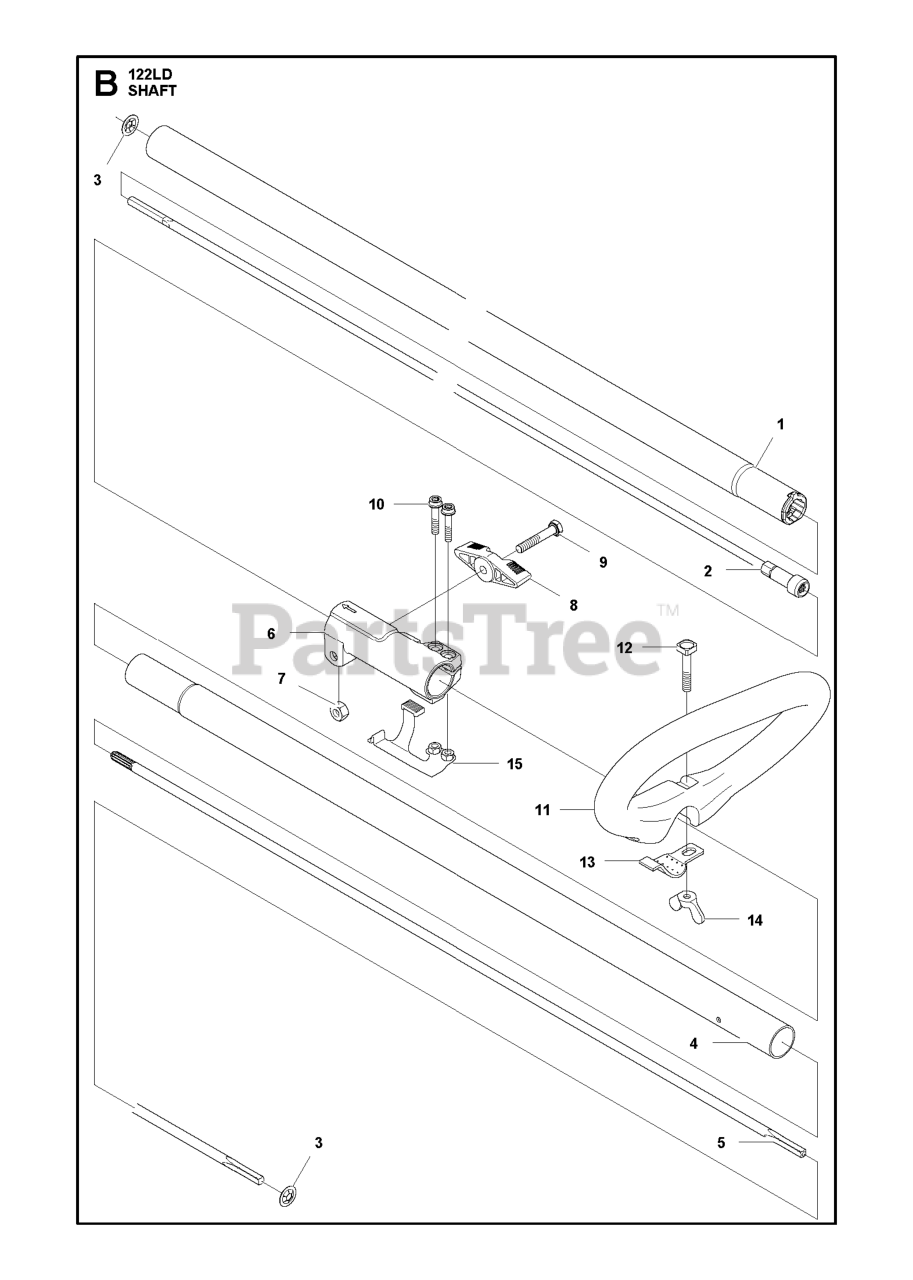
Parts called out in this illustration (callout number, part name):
2	DRIVE SHAFT
3	LOCK WASHER
5	DRIVE SHAFT ASSY
6	CLAMPING SLEEVE ASSY
9	BOLT FLANGE
10	BOLT FLANGE
15	LOCKING PLATE ASSY CLAMPING SL
